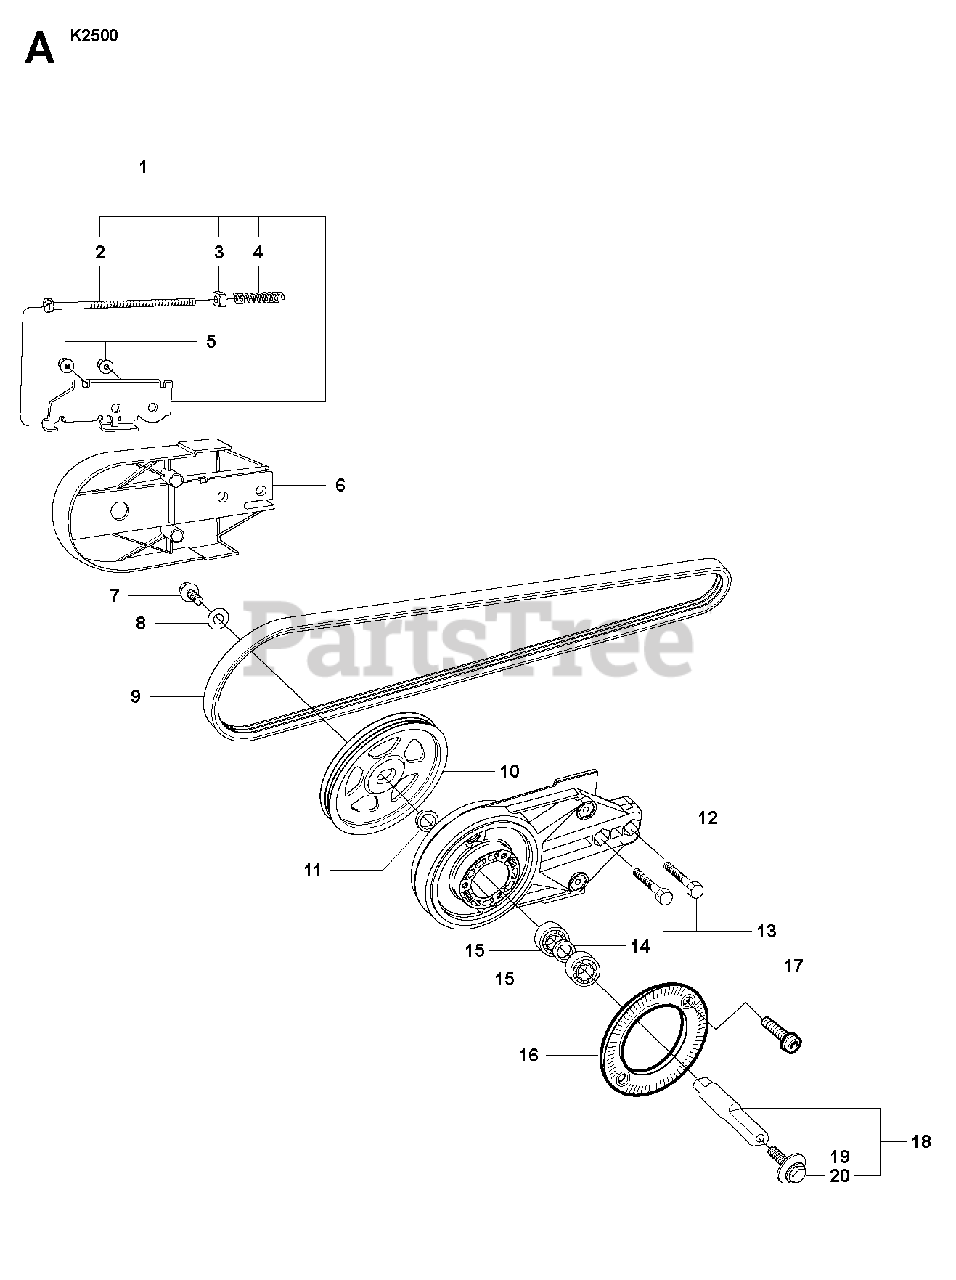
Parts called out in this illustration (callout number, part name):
1	BELT TENSIONER ASSYIncl. 2 - 4
10	PULLEY
15	BALL BEARING
17	SCREW IHSCFM
